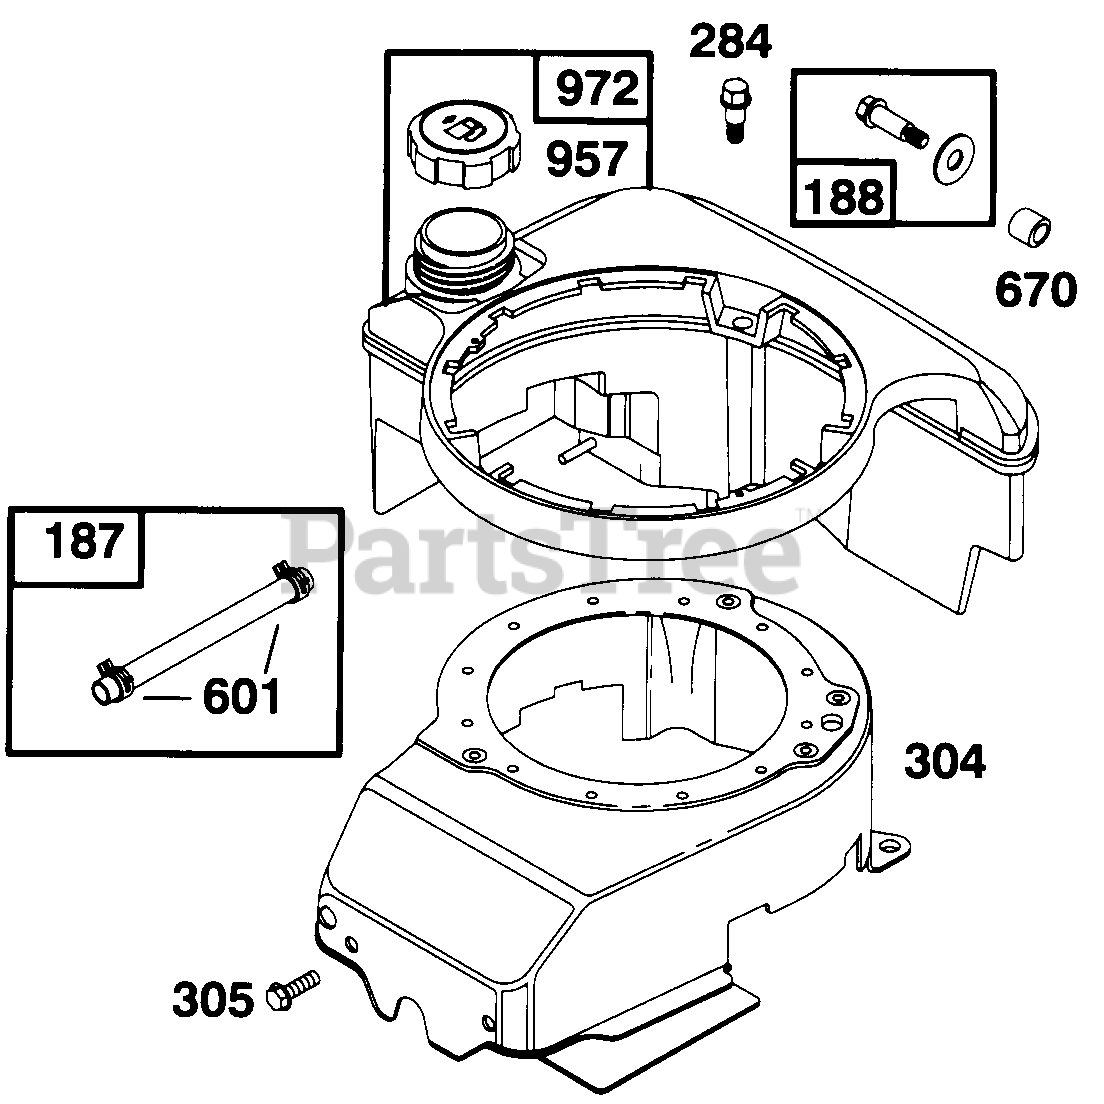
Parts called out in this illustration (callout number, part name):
187	Hose-Fuel
188	Screw-Hex. Head
284	Screw-Hex. Head
304	Housing-Blower
305	Screw-Sem
601	Clamp-Hose
670	Spacer-Tank
957	Cap-Fuel Tank
972	Tank-Fuel
